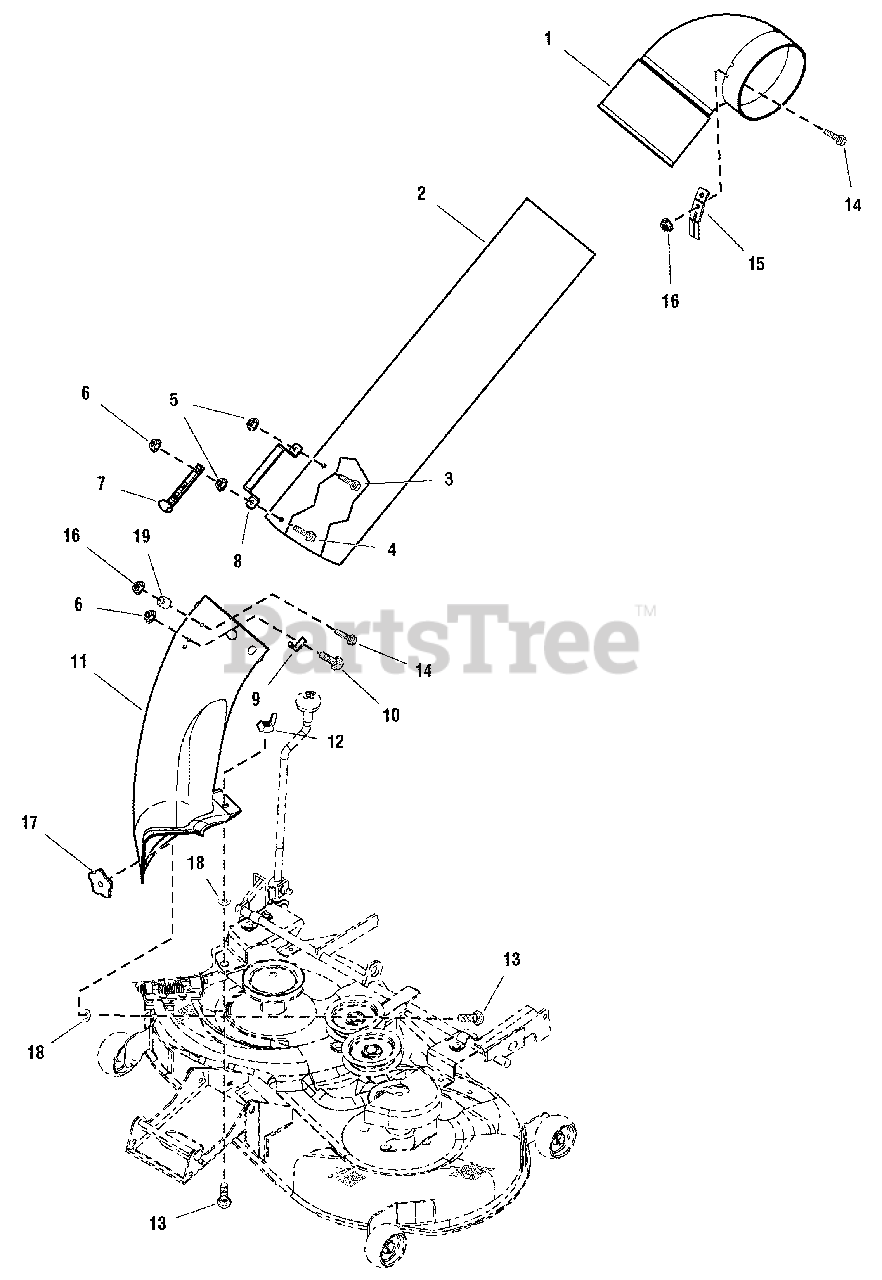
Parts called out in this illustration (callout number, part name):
1	ELBOW, Vac Collector 7 DIA Plastic Black
2	TUBE, Clear Poly Twin Catcher 42"
3	SCREW, Machine 1/4-20 x 1/2
4	SCREW, Machine 1/4-20 x 1
5	NUT, Hex KEPS 1/4-20 Black
6	NUT, Hex Flange Toplock Small, 1/4-20 Black
7	STRAP, Hood, Rubber Black
8	HANDLE, Connect Tube
9	PIN, Latch
10	CARRIAGE BOLT, 1/4-20 x 5/8 G5 Black
11	TUBE, Boot Poly Black
12	NUT, 5/16-18 Wingnut
13	CARRIAGE BOLT, 5/16-18 x 3/4 G5 Black
14	SCREW, Truss Head Torx Drive, 5/16-18 x 7/8 Black
15	STRAP, Bagger 42" Mower Black
16	NUT, Hex Lock ESNA Light, 5/16-18NC3B Black
17	KNOB, Internal Thread 5/16-18 23/32 Long 5 LOBE Black
18	NUT, Push PAL 5/16 DIA Thread 5/8 OD Black
19	SPACER, .344 ID x .499
